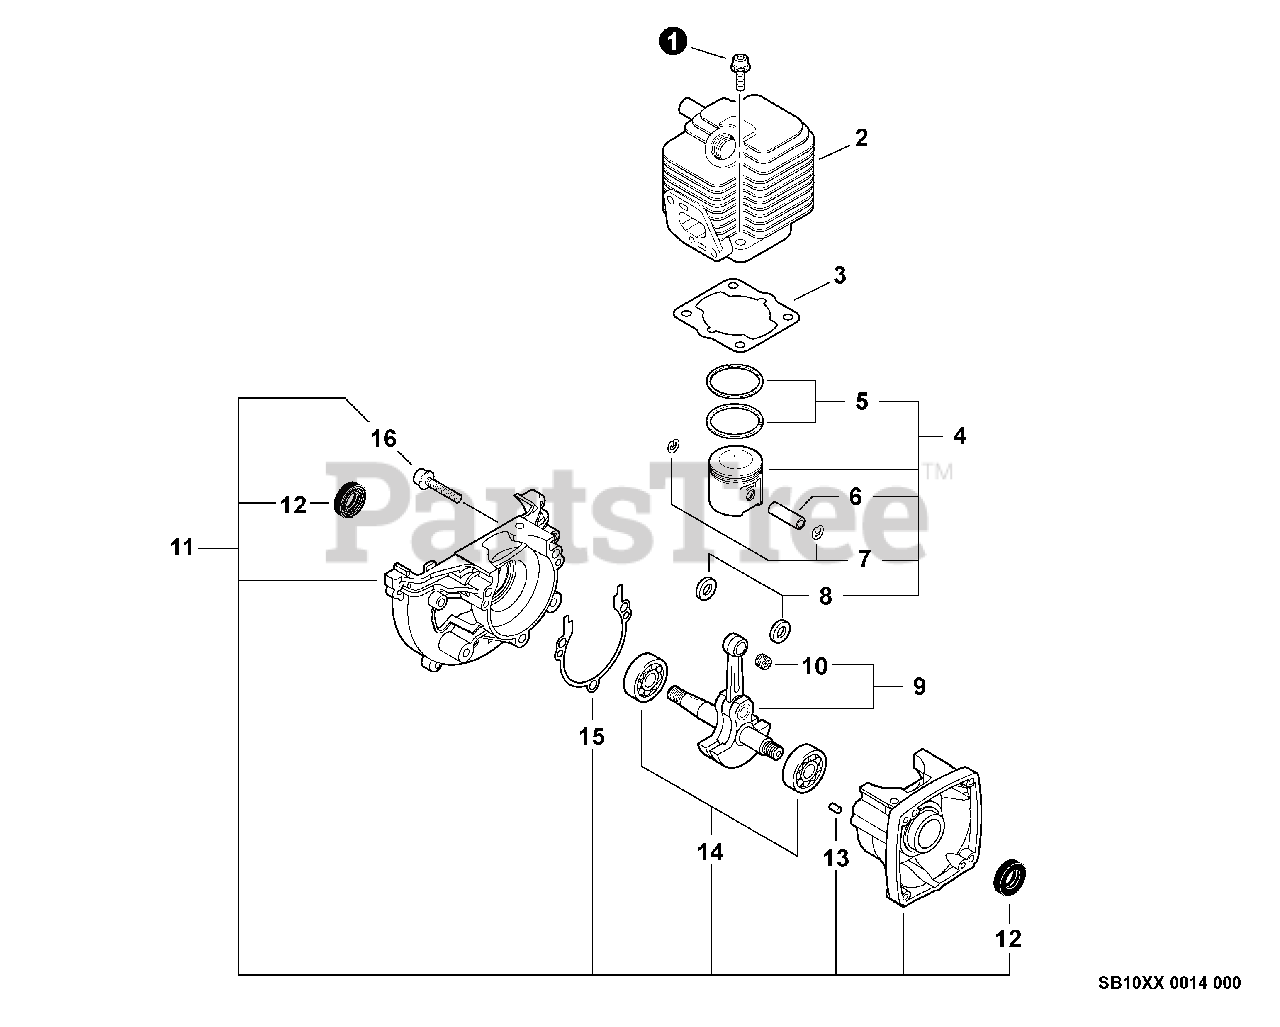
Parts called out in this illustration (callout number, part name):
1	BOLT 5×22
2	CYLINDER
3	GASKET, CYLINDER
4	PISTON KIT
5	RING, PISTON
6	PIN, PISTON 8
7	RING, SNAP
8	WASHER, THRUST
9	CRANKSHAFT ASSY
10	BEARING, NEEDLE
11	CRANKCASE KIT
12	SEAL, OIL 12
13	PIN, LOCATING 4
14	BEARING, BALL - 6201 C3
15	GASKET, CRANKCASE
16	BOLT 5×28
